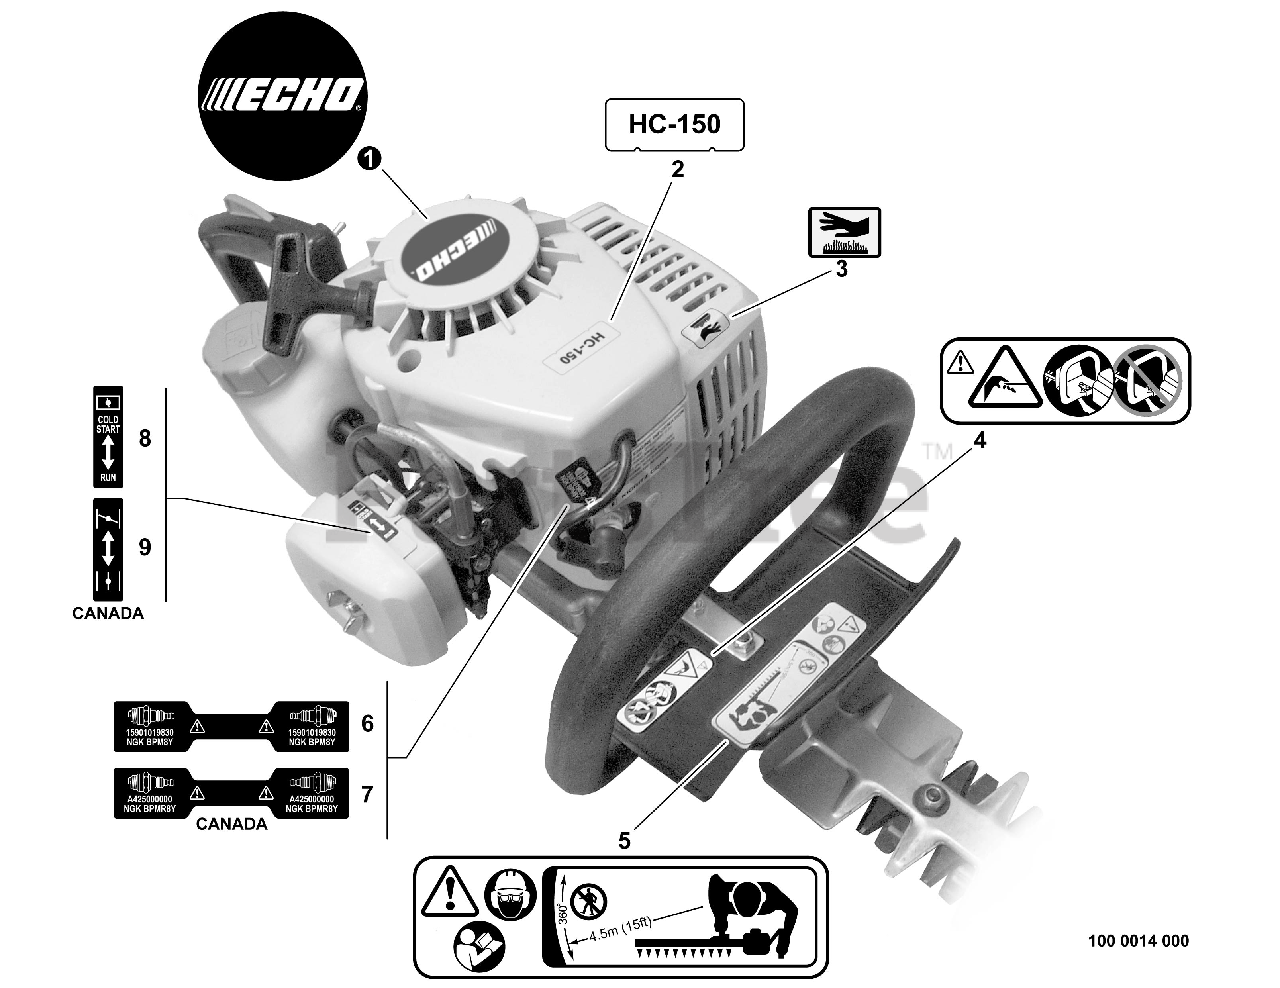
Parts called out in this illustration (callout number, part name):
1	LABEL - ECHO
2	LABEL - MODEL HC-150
3	LABEL - HOT SURFACE
4	LABEL - CAUTION
5	LABEL - CAUTION
6	LABEL - SPARK PLUG -- BPM-8Y
7	LABEL - SPARK PLUG -- BPMR-8Y
8	LABEL - CHOKE
9	LABEL - CHOKE
